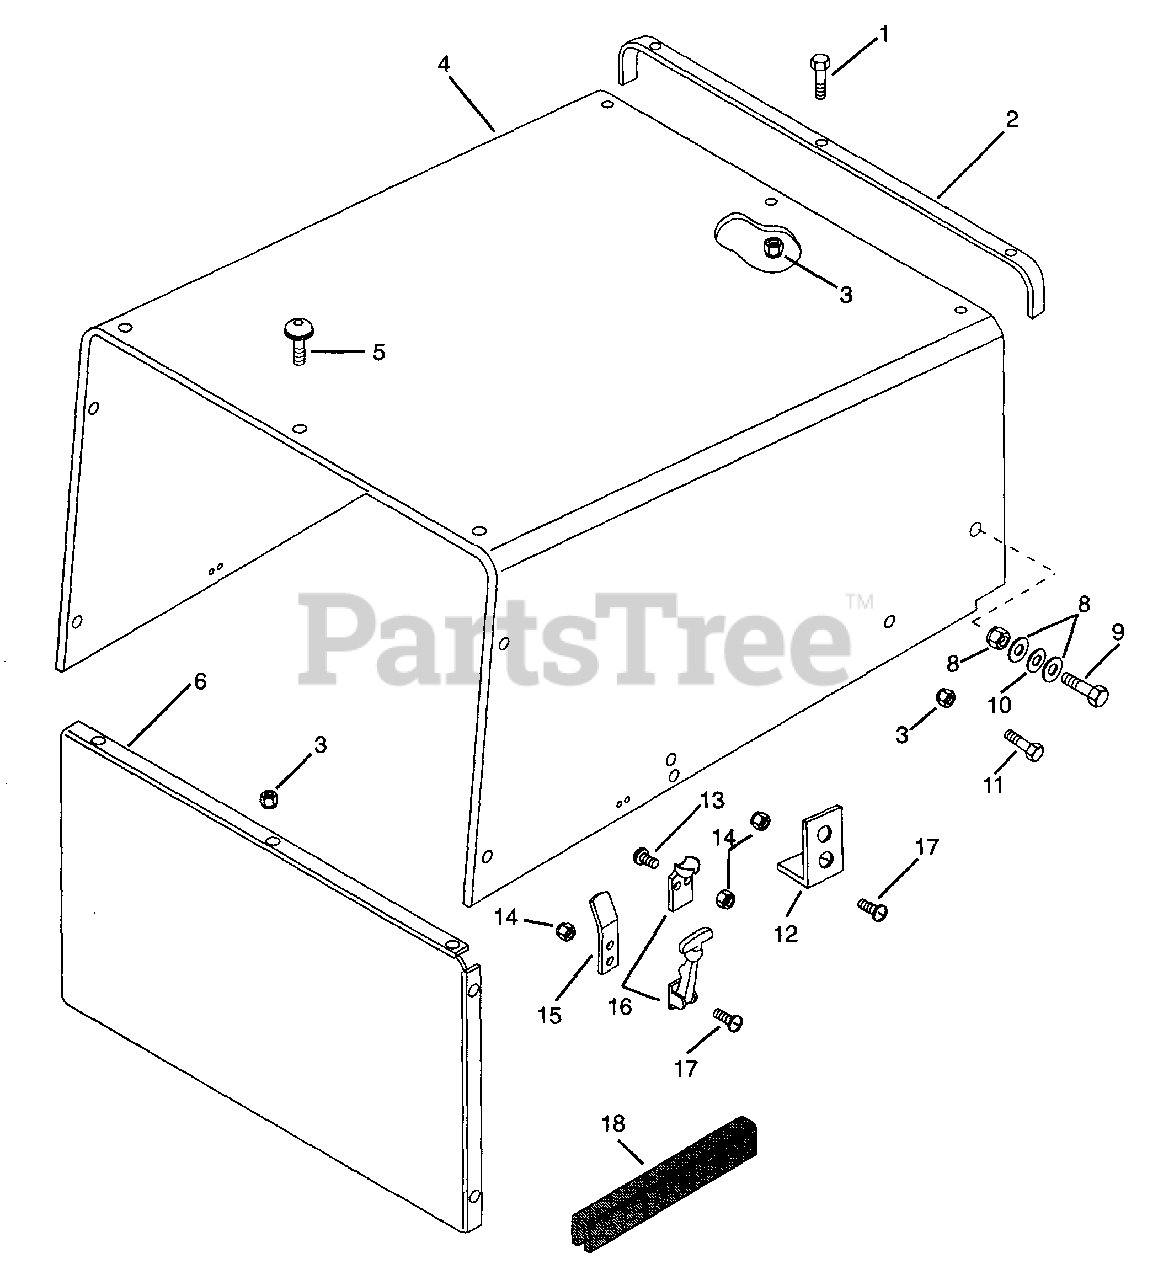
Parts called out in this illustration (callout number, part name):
1	Screw-Machine .25-20 X .75
2	Brace, Hood
3	Nut-Locking-Center .25-20
4	Hood, Engine
5	Screw-Machine .25-20 X .50
6	Panel, Hood
7	Nut-Locking-Center .38-16
8	Washer-Flat-Steel .406 x .812 x .065
9	Bolt-Hex .38-16 x 1.00 Grade 5
10	Washer-Flat-Nylon .375 X .75 X .060
11	Bolt-Hex .25-20 x .75 Grade 5
12	Bracket
13	Screw-Machine 10-24 x .50
14	Nut-Locking w/Insert 10-24
15	Plate, Guide
16	Latch
17	Screw-Machine 10-24 x .75
18	Strip, Cowl
